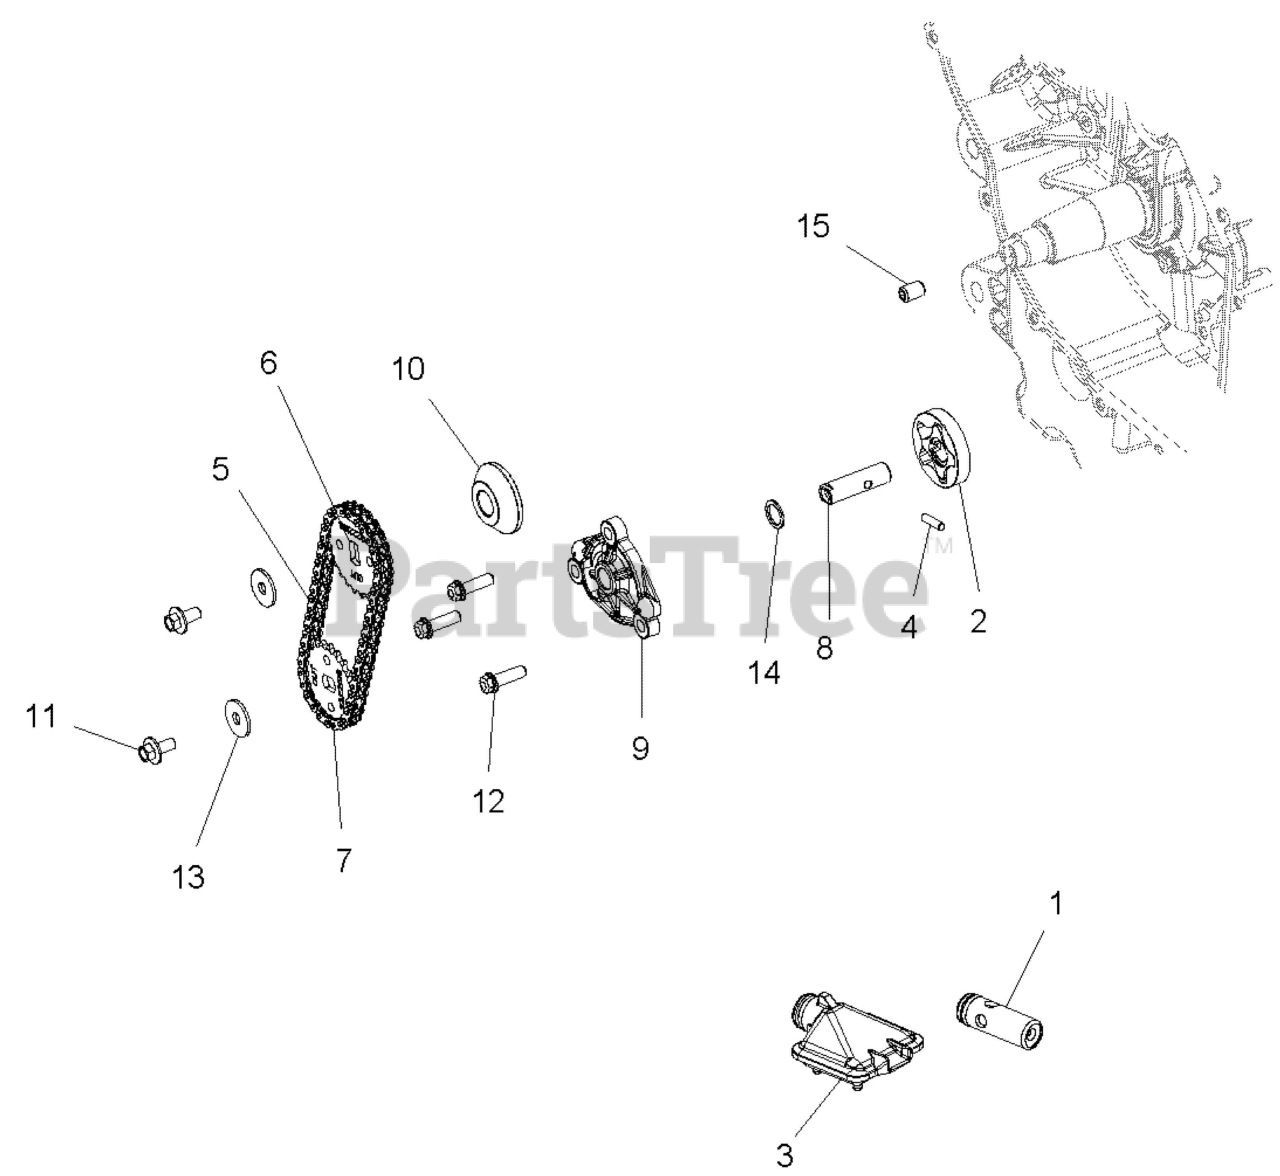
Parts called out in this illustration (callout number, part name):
1	ASM, REGULATOR VALVE
2	ASM-GEROTOR
3	ASM-OIL PICKUP
4	PIN-SOLID,M4X15.8
5	CHAIN-OIL PUMP DRIVE
6	SPROCKET-23T,DRIVE
7	SPROCKET-21T,DRIVEN
8	SHAFT-OIL PUMP
9	COVER-OIL PUMP,MACH
10	SPACER-SPROCKET
11	SCREW,HXFLGHD,M6X12
12	SCR-M6X20,HXFLG,0600214
14	WASHER-11.2X15.0X1.0
15	JET-OIL,OIL PUMP
